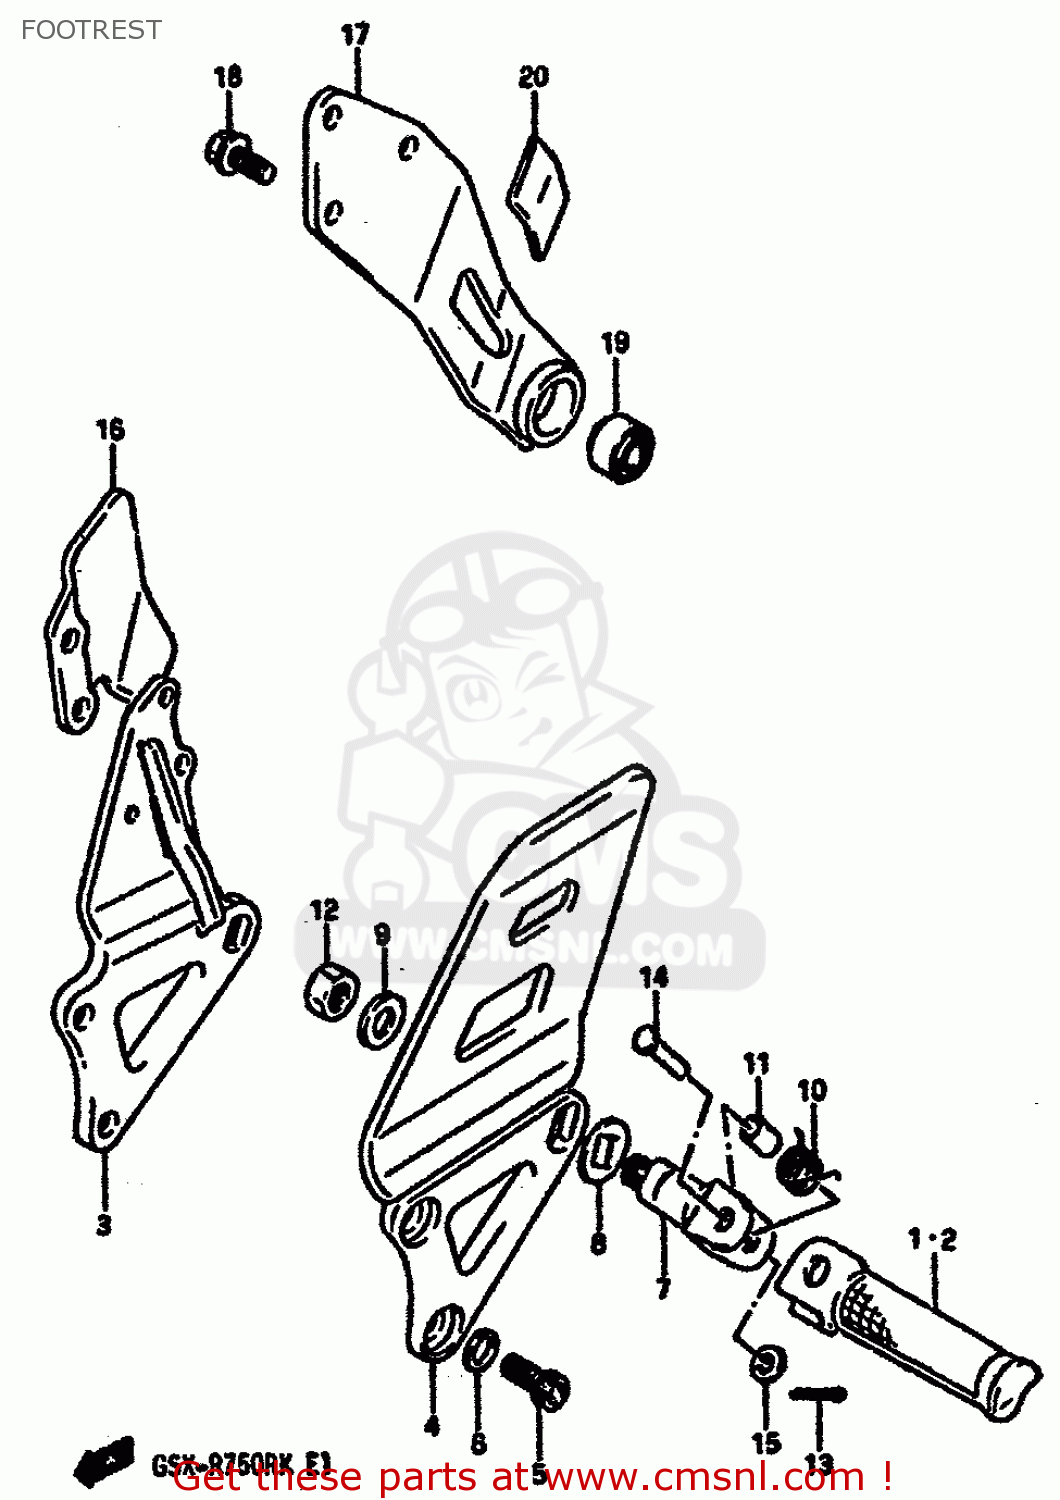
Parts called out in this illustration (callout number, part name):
1	BAR,FOOTREST,R
2	BAR,FOOTREST,L
3	BRACKET,FOOTREST RH
4	BRACKET,FOOTREST LH
5	BOLT,FOOTREST BRACKET
6	WASHER
7	BOSS,FOOTREST
8	PLATE,FOOTREST INNER
9	WASHER,FR FOOTREST
10	SPRING
11	SPACER(8.1X12X22)
12	NUT 12MM
13	PIN 20X15
14	PIN
15	WASHER
16	GUARD,FRONT FOOTREST RH
17	BRACKET,MUFFLER
18	BOLT
19	BUSH(10.2X25X19)
20	TAPE,FRAME PROTECTOR
